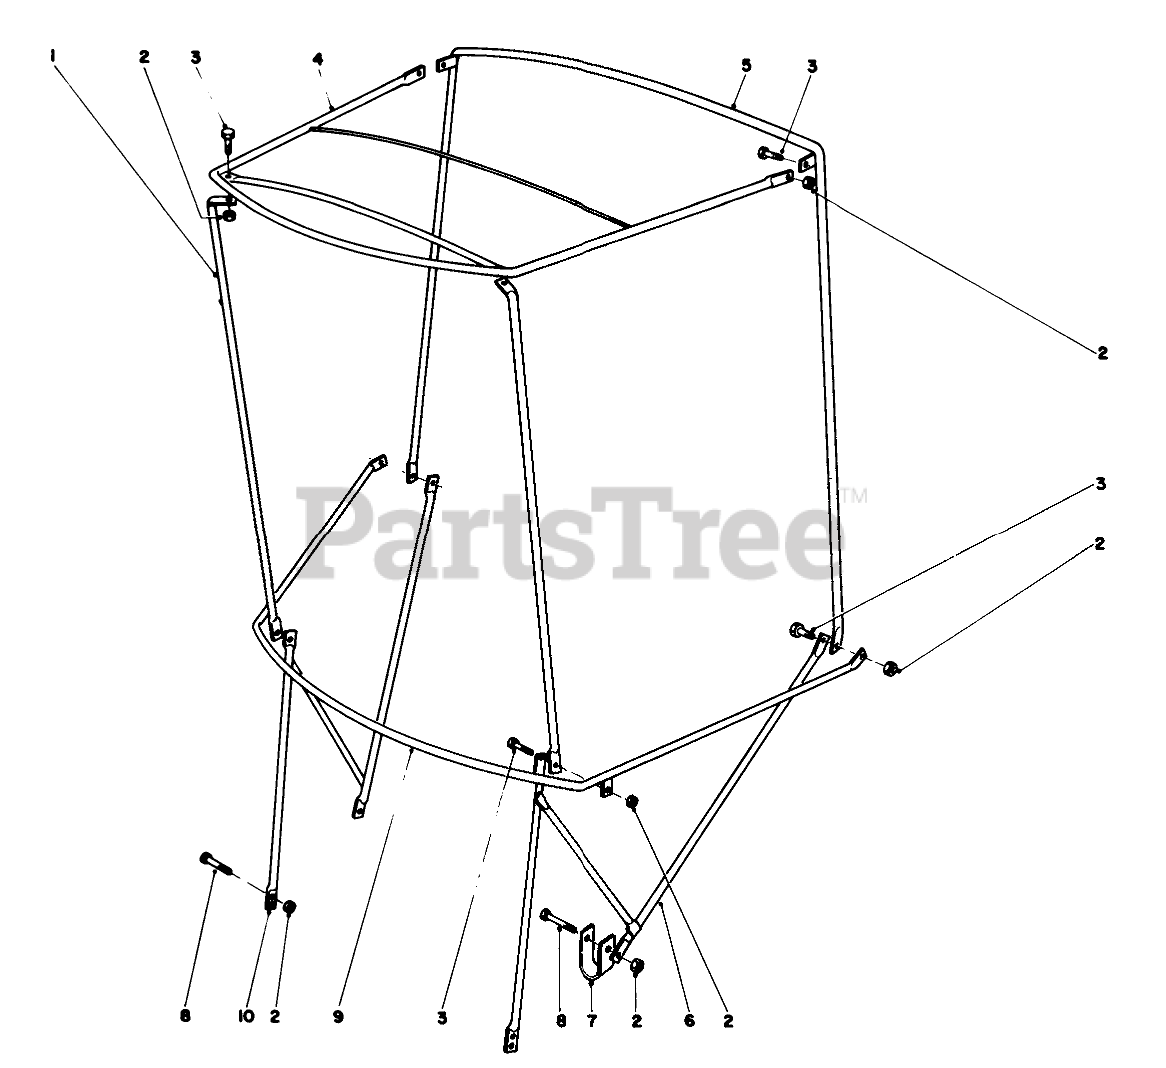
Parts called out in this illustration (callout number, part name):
2	NUT-HEX, SIDE DEFORM
3	SCREW-HH
4	FRAME-TOP
5	BOW-VERTICAL, REAR
6	ATTACHING BRKT L
7	U CLAMP
8	SCREW-HH
9	BOW-CURVED
10	ATTACHING BRKT R
